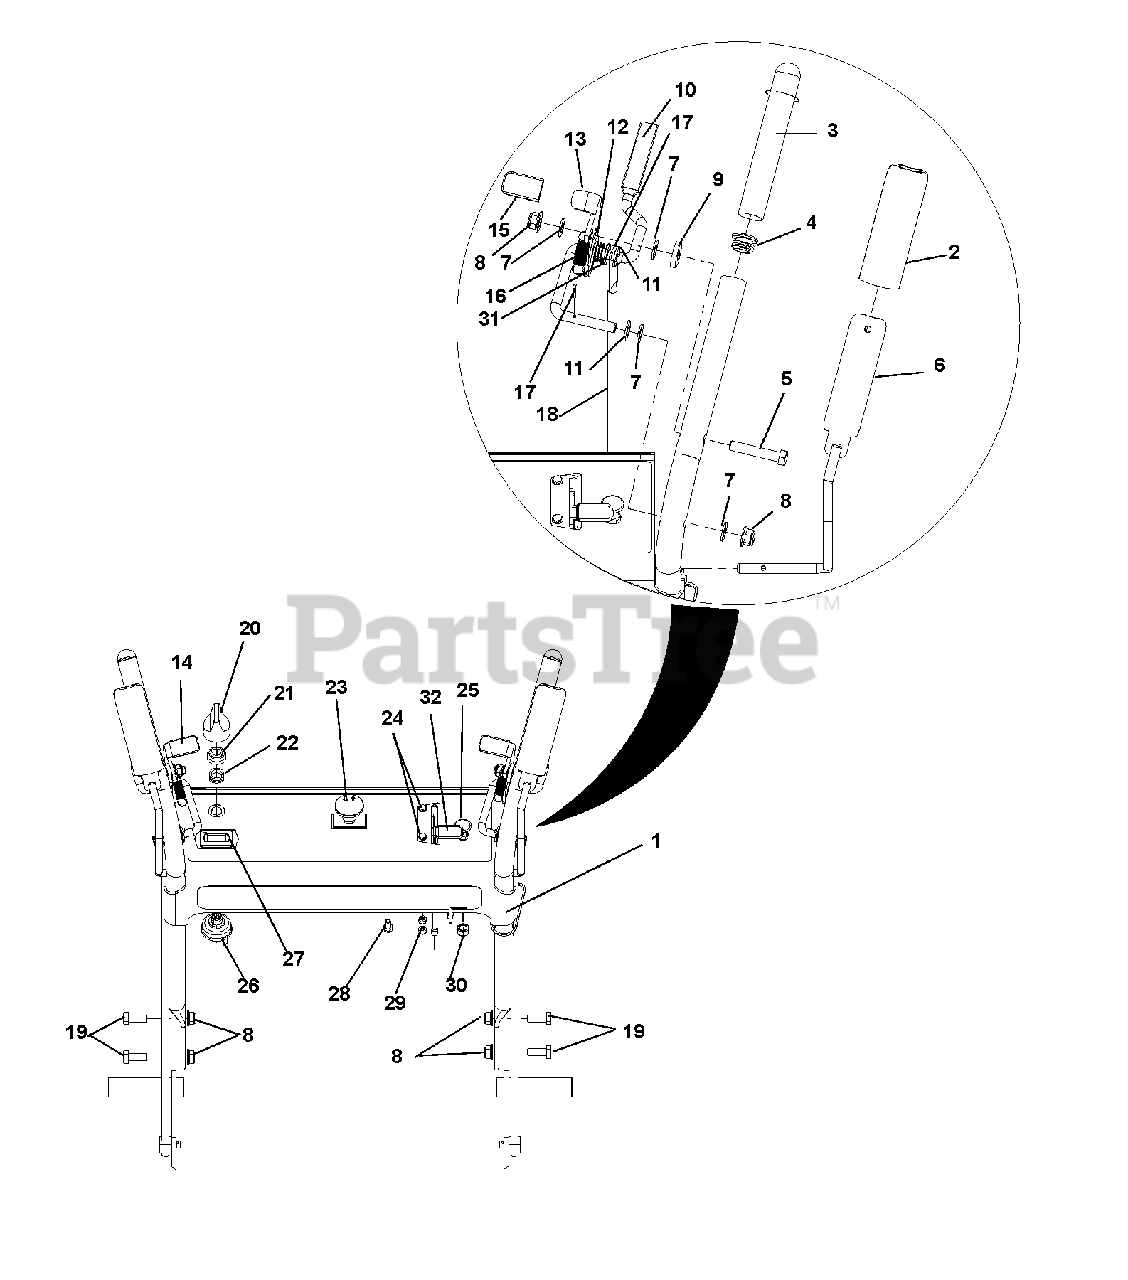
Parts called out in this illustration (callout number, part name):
1	Weldment, Pro Handlebar w/Decals
2	Grip, Clutch Lever
3	Grip, Handlebar
4	Caplug, Handlebar
5	Bolt-Hex .38-16 x 2.00 Grade 5
6	Weldment-Left Hand Lever-Operator Presence
7	Washer-Flat-Nylon .375 x .75 x .060
8	Nut-Locking-Nylon-Flange .38-16
9	Washer-Flat-Steel .406 x 1.00 x .188
10	Lever, Hand Control Left Hand
11	Washer-Flat-Steel .406 x .812 x .065
12	Washer-Flat-Steel .50 x 1.25 x .083
13	Latch, Left Hand Thumb
14	Latch, Right Hand Thumb
15	Grip, Thumb Latch
16	Spring-Tension .041 x .500 x 1.750
17	Pin-Center .09 x .75 Extended Prong Square Cut
18	Rod, Steering
19	Bolt, Hex .38-16 x 1.00 Grade 5
20	Key with Shield
21	Cap, Ignition Switch
22	Nut, Panel .562-24
23	Switch, Clutch
24	Screw, Machine 10-24 x .75 Hex Washer Head
25	Cable, Choke
26	Key Switch
27	Meter, Hour INDCTV Recoil Engine
28	Bolt, Hex .25-20 x .75 Grade 5
29	Nut, Locking-Nylon 10-24 with Insert
30	Nut, Hex .375-24 Grade 2
31	Spring, Compression .045 x .600 x .750
32	Cable, Throttle with Liner
